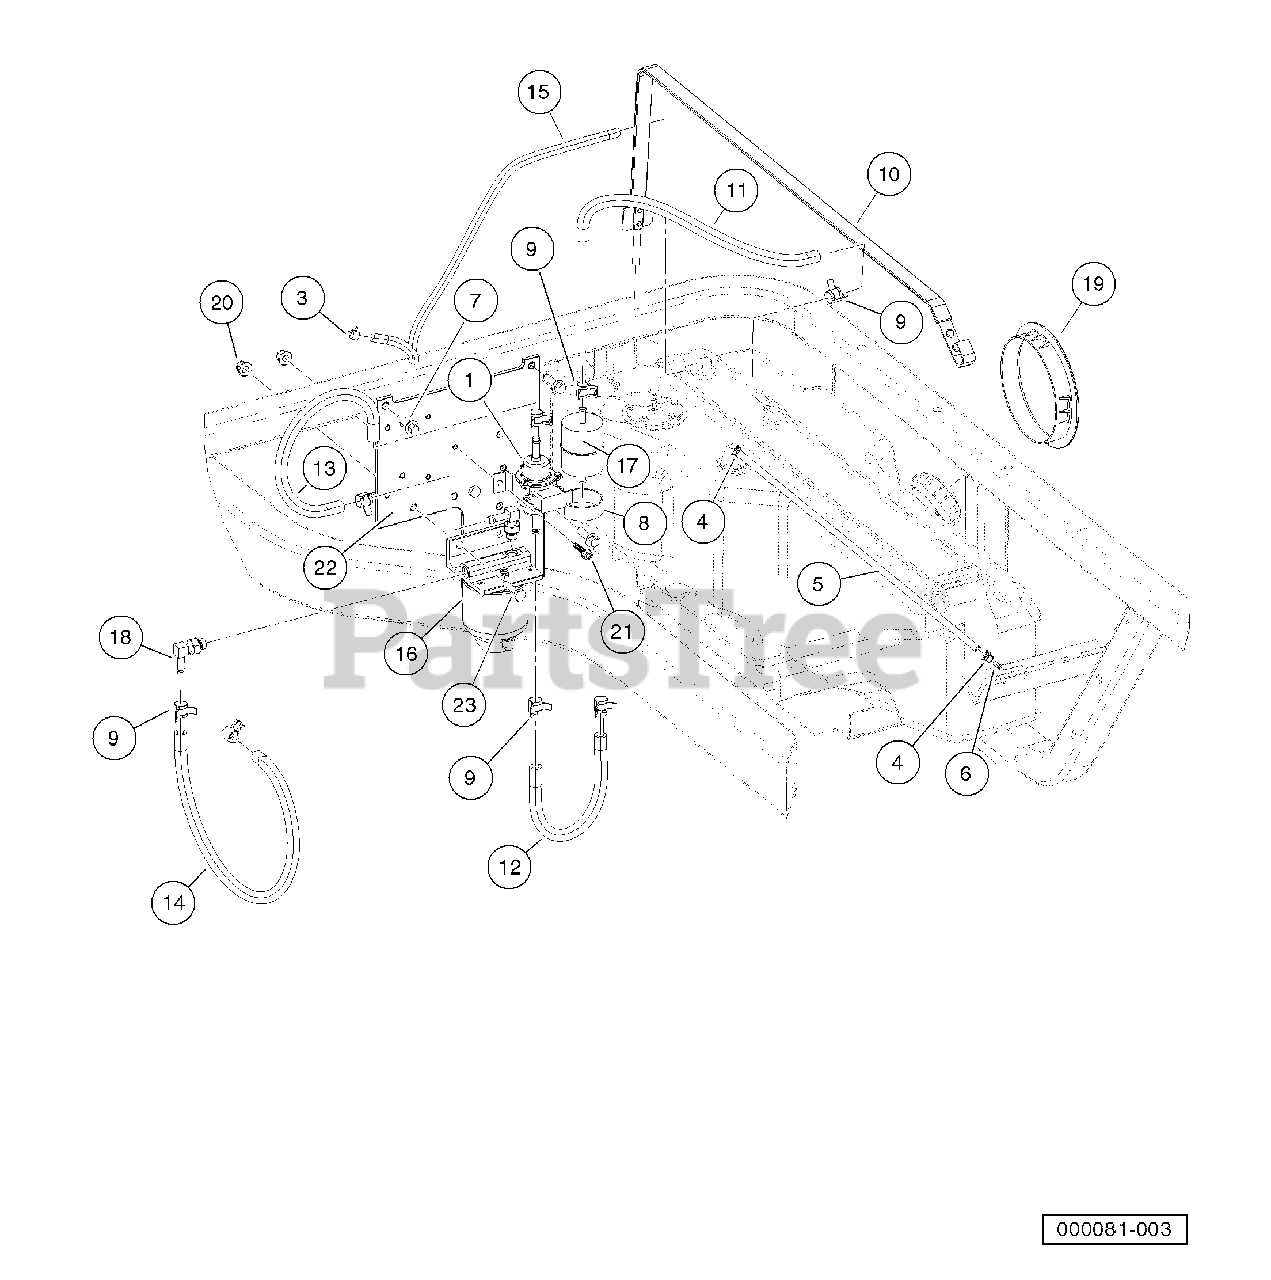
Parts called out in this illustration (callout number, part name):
1	Pump, Diesel Fuel Electric
2	Asm, Fuel System, Kubota
3	Clamp, Green Hose
4	Clamp, 0.301 ID Hose
5	Hose, Fuel, Vent, 22" Long
7	Screw, M8X1.25X30, Hex
8	P-Clamp, Insulated 1.75 In
9	Clamp, Hose, Ctb 14mm
10	Strap, Tank, Fuel
11	Hose, Tank To Prefilter Diesel
12	Hose, Fuel Prefilter To Pump
13	Hose, Fuel Pump To Filter
14	Hose, Fuel Filter To Eng
15	Hose, Fuel Return
16	Filter Assy, Fuel
17	Filter, Fuel
18	Adapter, 90, 5/16 Tube
19	Bezel, Fuel Fill
20	Lock Nut, Flg M8 X 1.25 Nylon
21	Screw, M6 X 1 X 25 Thd Form
22	Plate, Fuel/Oil System
23	Bolt, M8 X 1.25 X 30
